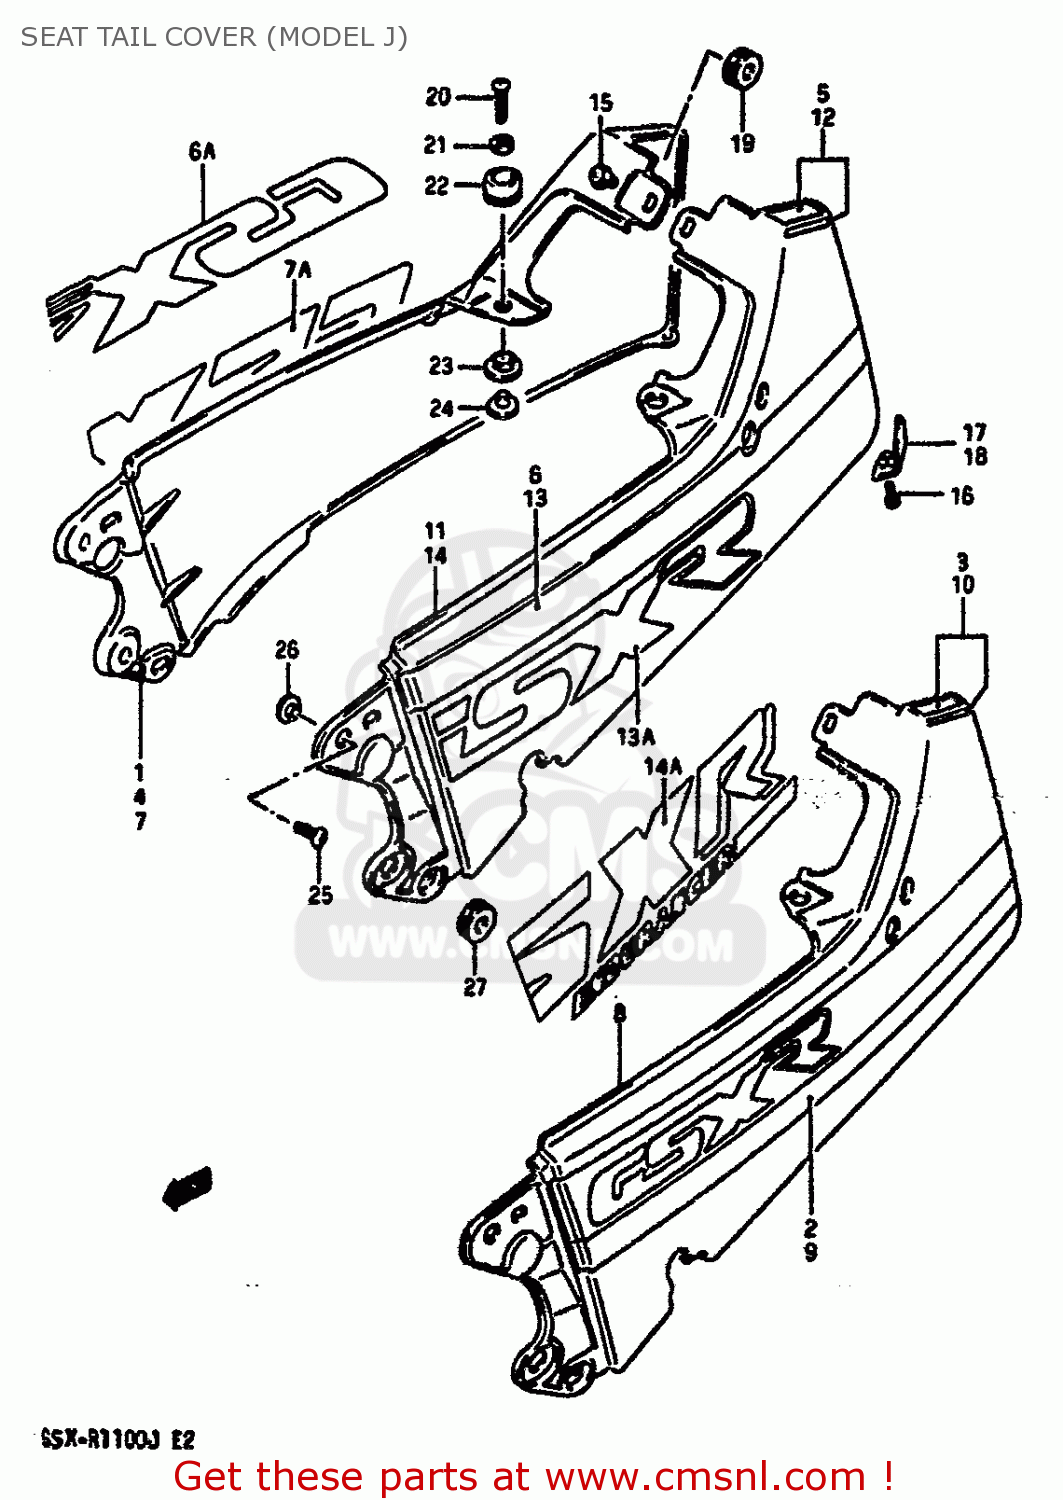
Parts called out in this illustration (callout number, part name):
1	COVER COMP,SEAT TAIL
2	TAPE,SEAT TAIL COVER,RIGHT
3	TAPE,SEAT TAIL COVER,RIGHT
4	COVER COMP,SEAT TAIL
5	TAPE,SEAT TAIL COVER,RIGHT
6	TAPE,SEAT TAIL COVER,RIGHT
6A	EMBLEM,RIGHT
7	COVER SEAT TAI
7A	EMBLEM,RH (GOLD)
8	COVER,SEAT TAIL
9	TAPE,SEAT TAIL COVER,LEFT
10	TAPE,SEAT TAIL COVER,LEFT
11	COVER,SEAT TAIL
12	TAPE,SEAT TAIL COVER,LEFT
13	TAPE,SEAT TAIL COVER,LEFT
13A	EMBLEM,LEFT
14	COVER,SEAT TAIL LH (BLACK)
14A	EMBLEM,LH (GOLD)
15	CLIP
16	SCREW
17	PLATE,SEAT TAIL COVER,RH
18	PLATE,SEAT TAIL COVER,L
19	CUSHION
20	SCREW
21	WASHER
22	SCREW
23	WASHER
24	WASHER
25	SCREW
26	WASHER
27	CUSHION
